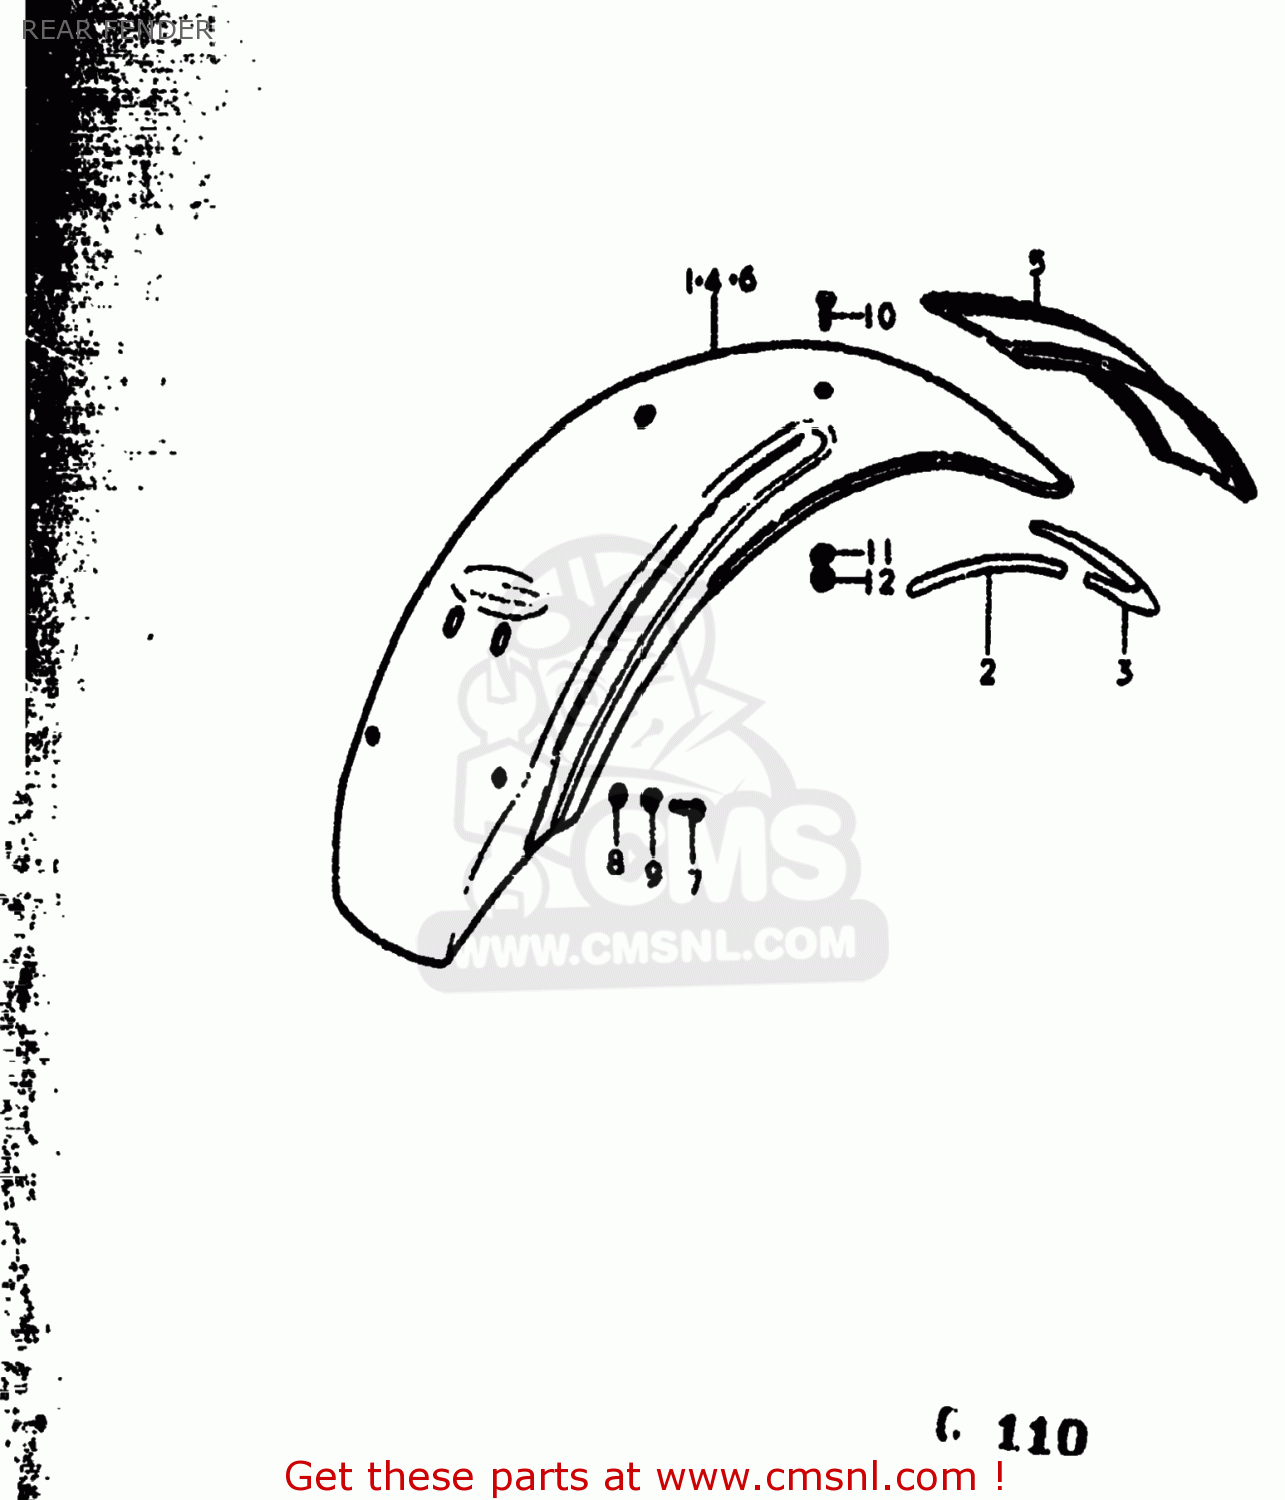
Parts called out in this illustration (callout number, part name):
1	FENDER,REAR
2	TAPE,FRONT FENDER
3	TAPE,FRONT FENDER
4	FENDER,REAR
6	FENDER,REAR
7	BOLT
8	WASHER
9	LOCK WASHER
10	BOLT
11	LOCK WASHER
12	NUT
